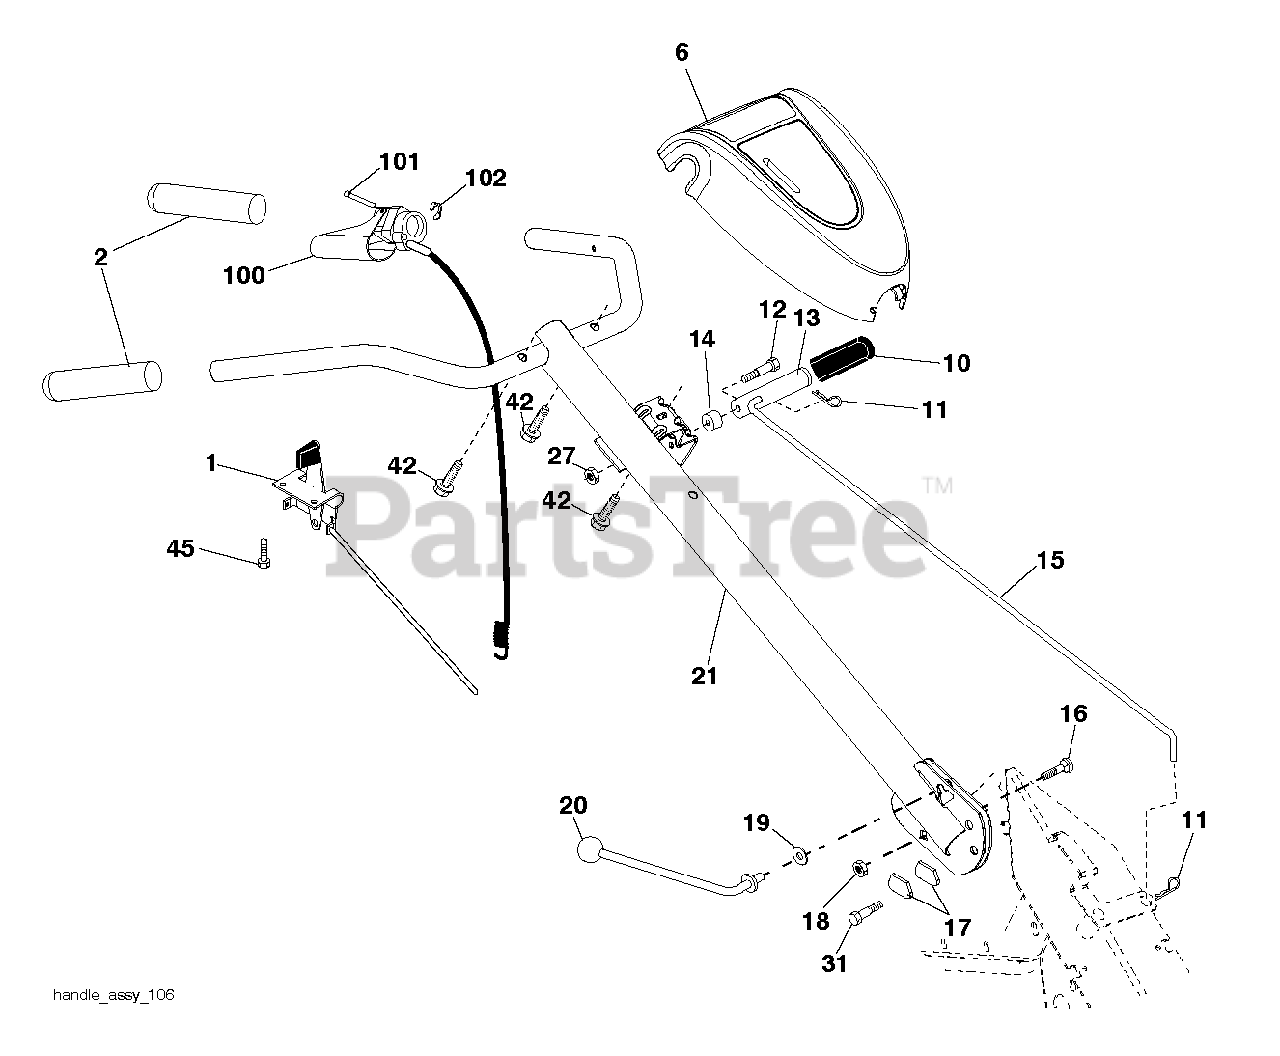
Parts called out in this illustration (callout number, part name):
1	CONTROL.THROTTLE.SNAP.IN
2	GRIP.1X5.06
6	CONSOLE.GREY.CRT.W.S.CRT900L
10	GRIP T
11	RETAINER M
12	SHOULDER BOLT ST
13	HANDLE.SHIFT.TILLER.498
14	GROMMET.RUBBER.CRT.TILLER
15	ROD.SHIFT.YARD PRO.UNIVERSAL.
16	BOLT D
17	LOCK.HANDLE.CRT
19	WASHER CRT
20	LEVER.LOCK.CRT
21	HANDLE.ASM.HUSQ/P.PRO.GREY
27	NUT T
31	BOLT.PIVOT
42	SCREW.#10 X 0.750.BOS
45	SCREW.#10 X 0.500
100	CONTROL.ASSEMBLY.TINE.TILLER
101	PIN, PIVOT
102	RETAINING.RING.#5103-25
